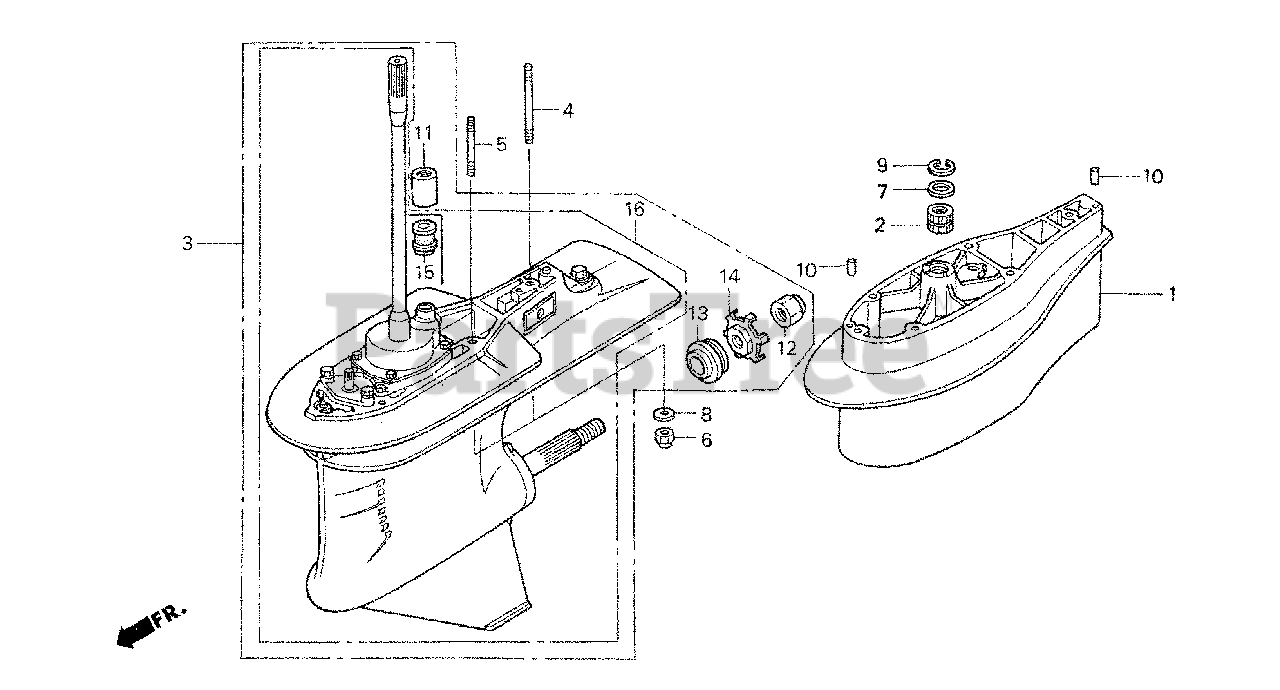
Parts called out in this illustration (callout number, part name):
3	CASE ASSY., GEAR (20") *NH282MU* (OYSTER SILVER METALLIC-U)
12	NUT, PROPELLER HUB
13	WASHER, PROPELLER THRUST
14	WASHER, TAB
